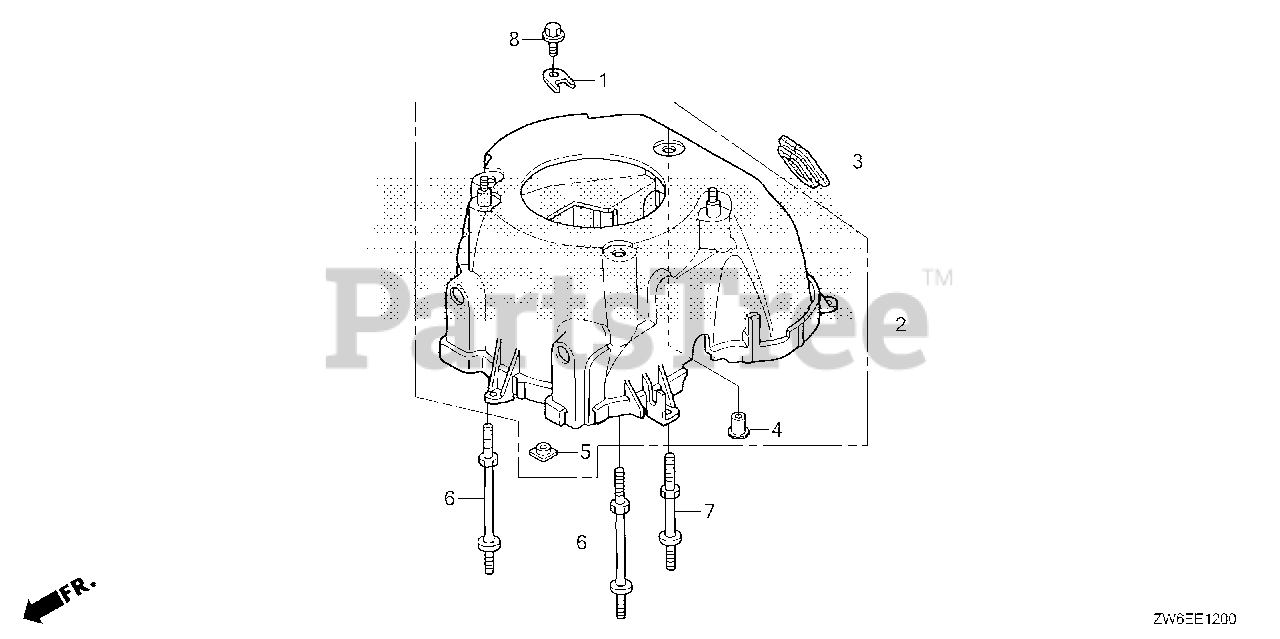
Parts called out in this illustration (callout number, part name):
1	HOLDER, CABLE
2	COVER, FAN
3	GROMMET, FAN COVER
4	COLLAR, FAN COVER
5	NUT, SPECIAL (5MM) (NOT AVAILABLE)
6	BOLT A, STUD
7	BOLT B, STUD
8	BOLT, FLANGE (5X10)
